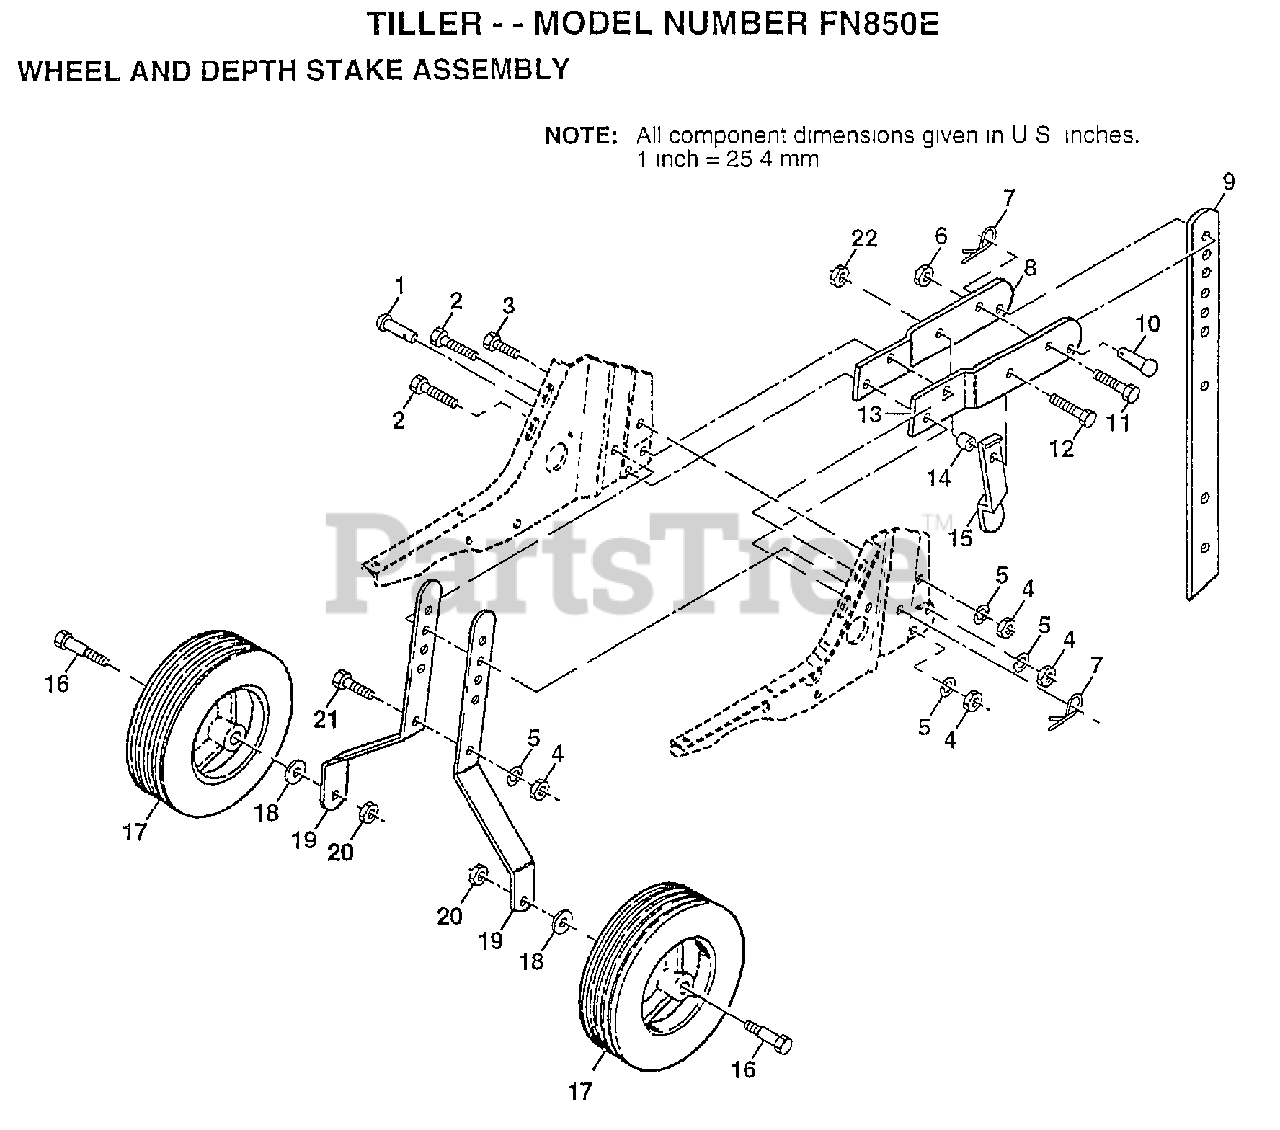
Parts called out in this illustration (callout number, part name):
1	DRILLED RIVET RT
3	BOLT
4	NUT.HEX.5/16-18
5	LOCKWASHER
6	NUT
7	SPRING.RETAINER
11	BOLT
12	BOLT.HEX.5/16-1.5
14	WASHER
15	STAKE SPRING TI
16	BOLT SHOULDER
18	WASHER
22	NUT
